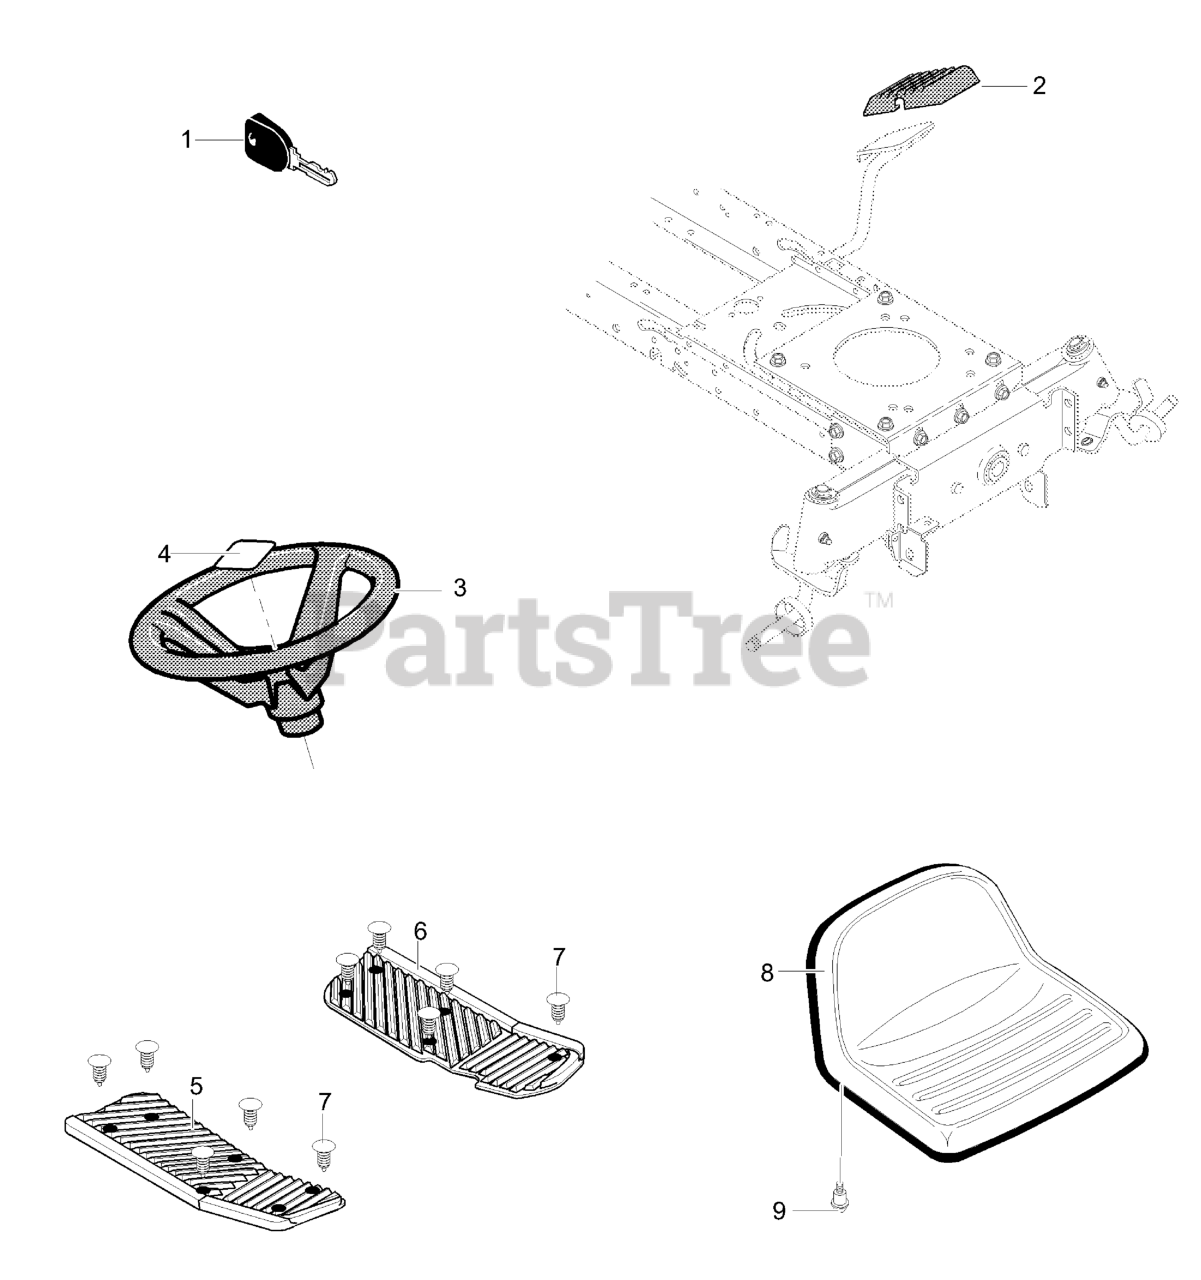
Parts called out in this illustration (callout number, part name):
1	Ignition Key
2	Cover, Pedal Brake/Clutch
3	Steering Wheel
4	Insert, 4-Spoke
5	Footrest Pad RH
6	Footrest Pad LH
7	Ratchet Faastener
9	Shoulder Bolt 5/16-18
